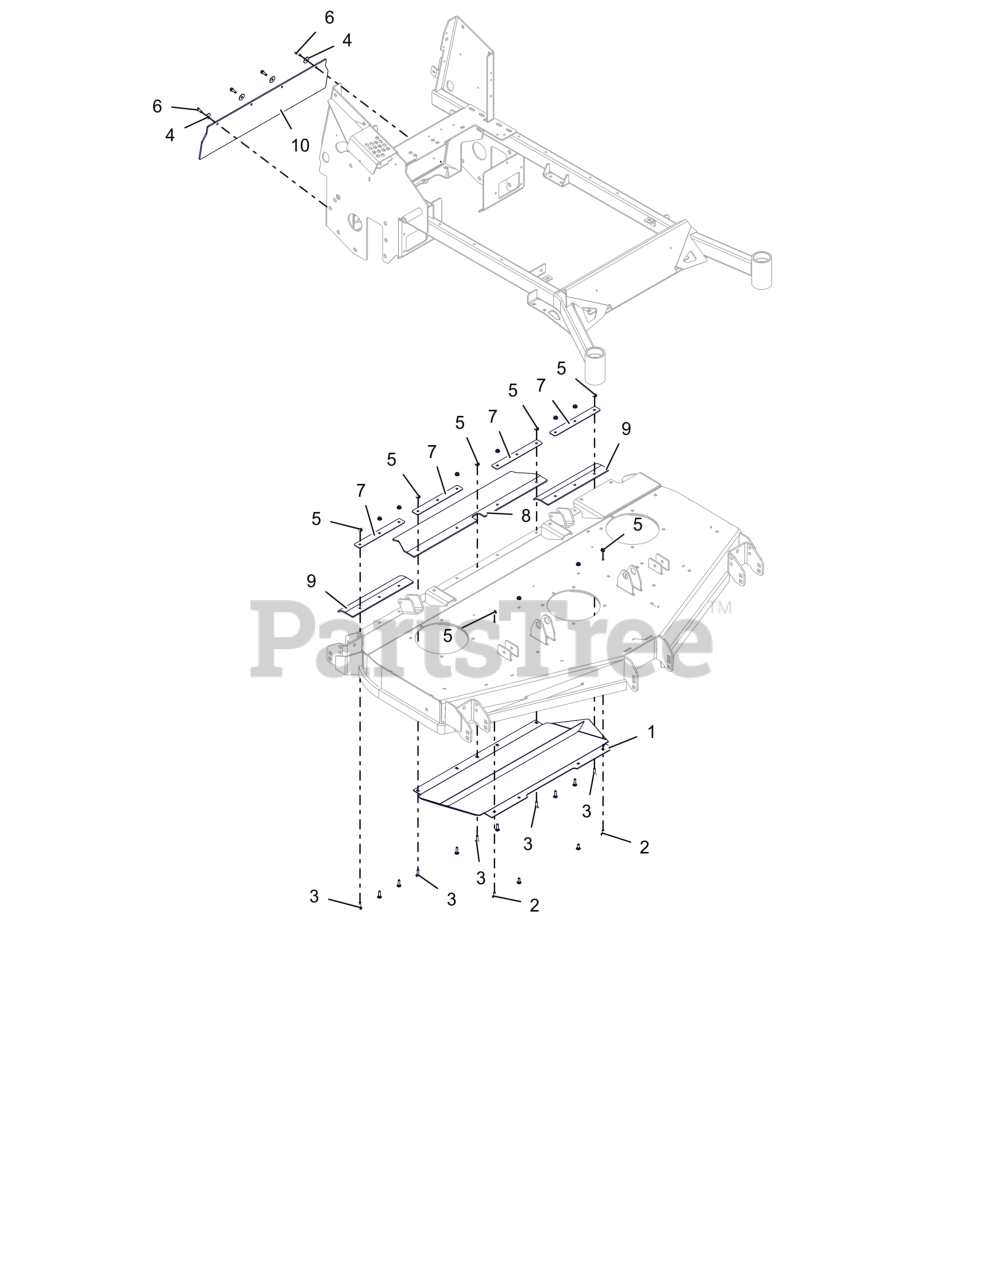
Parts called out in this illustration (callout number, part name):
1	WLDMT, DEFLECTOR BAFFLE (RED)
2	BLT, RHSN .25-20X.750 G5 ZCC
3	BLT, RHSN .25-20X1.00 G5 ZCC
4	WSHR,FLT .281X1.000X.063 ZCC
5	NUT-LK-CTR-FLG .25-20 ZC120
6	SCR,TAP .25-20X.75 HWH TR ZCC
7	PLATE, CHUTE MTG (BLACK)
8	CHUTE- REAR DISCHARGE 6.5 IN
9	FLAP- REAR DISCHARGE 60" TIRE
10	CHUTE, REAR DISCHARGE
